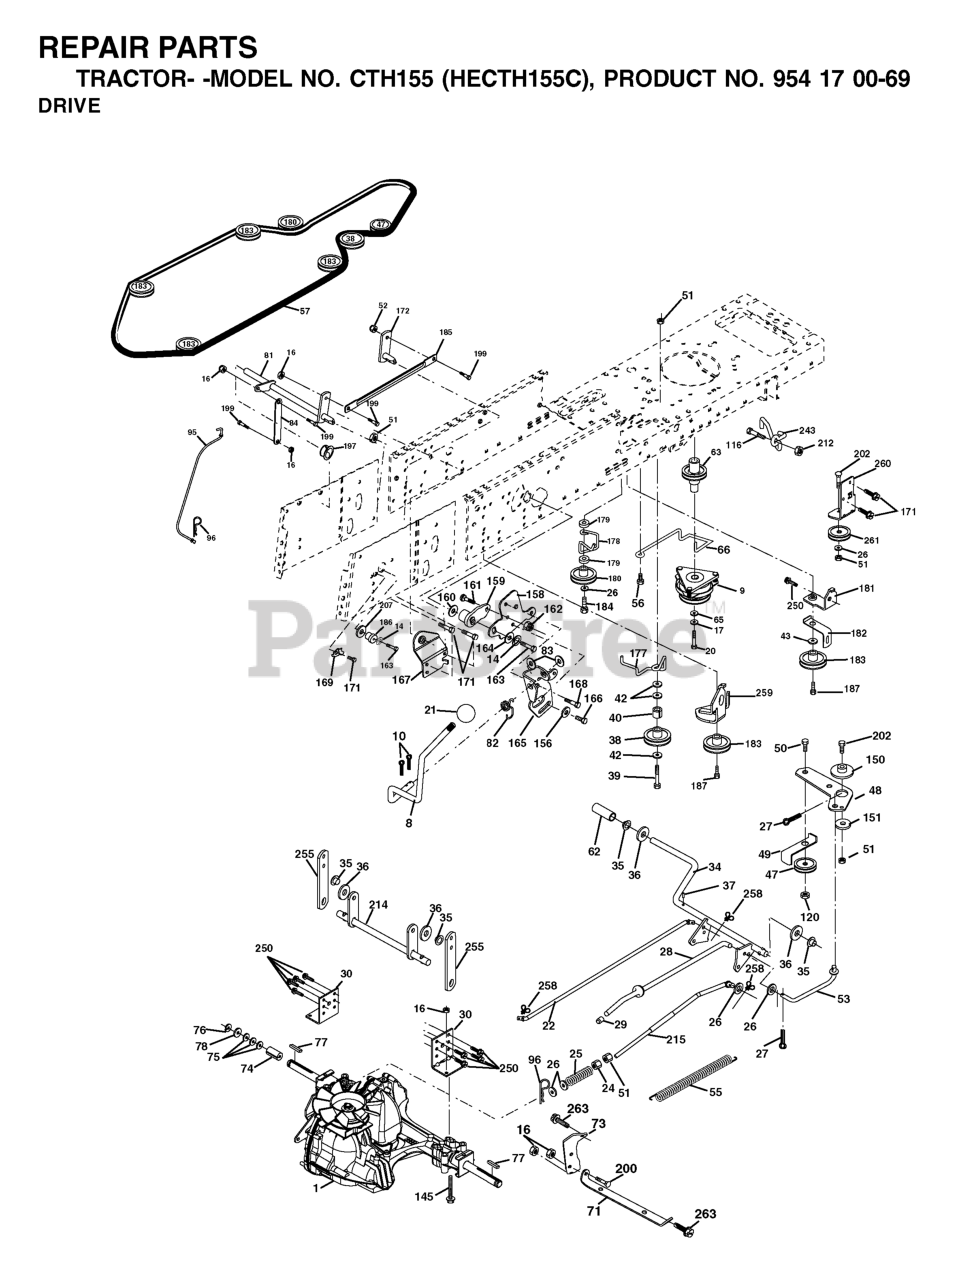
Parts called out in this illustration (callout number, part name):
8	ROD.SHIFT.FENDER.ADJ.LT.CRD
10	PIN COTTER
14	LOCKWASHER
16	NUT.71038.31-18.HEX.NYLOCK
20	BOLT
21	KNOB.DUCKHEAD.1/2
22	ROD
24	NUT
25	SPRING ROD LT
26	WASHER
27	COTTER PIN
28	ROD, PARKING BRAKE
29	PLUNGER CAP
30	BRKT, TRNSXLE MNT 20"
33	RP BOLT 5/16-18 X3/4 ZN/YEL GR
34	SHAFT, FOOT PEDAL
35	BEARING.NYLON
36	WASHER LT
37	DRIVE PIN
38	PULLEY.FLAT
42	WASHER
43	WASHER T
47	IDLER PULLEY
48	BELLCRANK, CLUTCH
49	RETAIN BELT
50	BOLT
52	LOCKNUT
53	LINK, CLUTCH LT
55	SPRING, RETURN LT
56	SCREW.3/8-16
57	V-BELT 113"
62	COVER, PEDAL (1 2)
63	PULLEY.ENGINE.CVX.LT
65	LOCKWASHER
66	KEEPER BELT ENGINE
71	STRAP TORQUE LH HYDRO
73	STRAP TORQUE RH HYDRO
74	SPACER AXLE
77	SQUARE KEY
81	ASM.CROSS.SHAFT.REAR.CRD.0510
82	SHIFT SPRING
83	WASHER
84	LINK.PNT.TRANSAXLE.0510.CRD
95	LINK
96	RETAINER M
116	BOLT D
120	NUT LOCK FLG 3/8-16 UNC
144	Washer 11/32 x 5/8 x 16 Ga SD
145	BOLT HEX 5/16-18 GR 5
150	BUSHING.BELLCRANK.GRD.DR
151	WASHER 12/32X2X10GA
156	WASHER.SRRTD.5/16
158	BRACKET
159	HUB
160	Washer 29/32 x 1 - 1/4 x 16 Ga.
161	BOLT
162	NUT.CROWNLOCK.1/4
163	BOLT
164	Washer 5/8 x .281 x 10 Ga.
165	RP BRACKET
167	BRACKET.SUPT.SHIFT.CRD
168	BOLT.SHOULDER.5/16-18X
169	PLATE.FASTENING.CROSS.SHAFT
171	SCREW LT
172	LINK
174	LOCKWASHER
180	PULLEY.FLAT.IDLER
181	BRACKET
182	BELT GUIDE
184	SCREW.HXWSH.3/8
185	LINK
186	HUB.TAPERED.ROUND.CRD
187	BOLT.5/16-18X1.25
197	NYLINER SNAP 5/8" ID
199	BOLT SHOULDER 5/16-18 UNC
200	BOLT
206	WASHER
207	WASHER NYL
212	NUT
214	LEVER
215	ROD
243	BRKT ASM MTNG
250	SCREW 3/8-16X3/4
255	SHAFT
258	CLIP RETAINER
259	BRACKET
261	FLAT IDLER PULLEY
263	SCREW, 3/8-16X3/4
